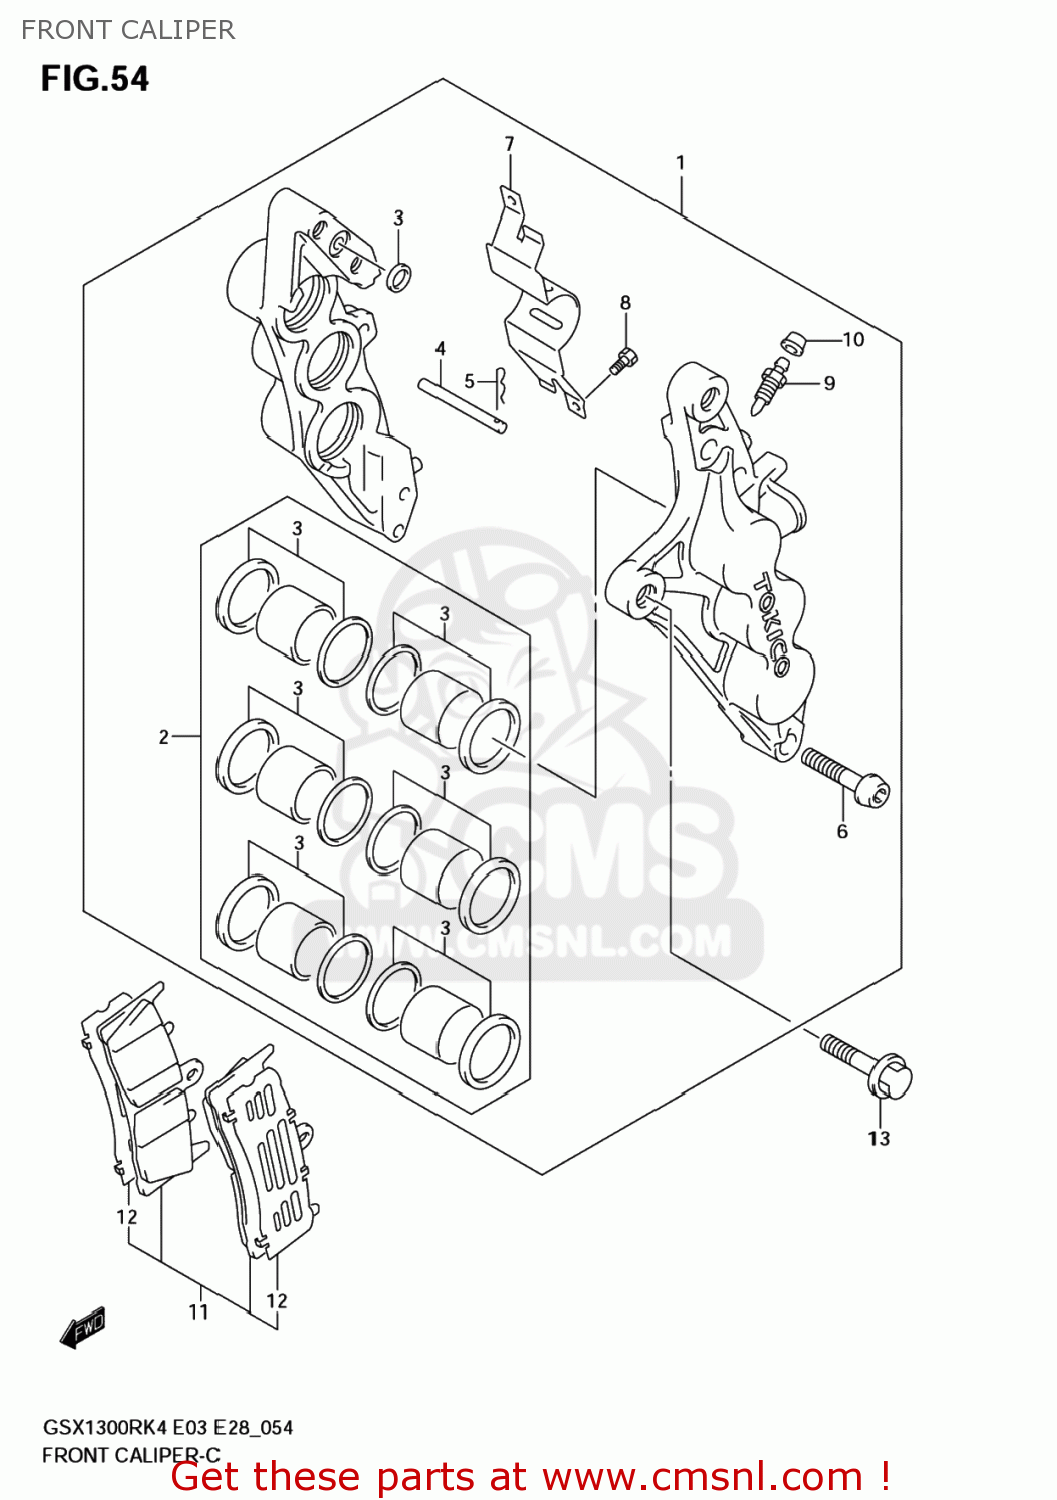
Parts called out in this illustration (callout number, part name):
1	CALIPER ASSY,FR,R(GOLD)
2	PISTON SET
3	SEAL SET,PISTON
4	PIN,PAD
5	CLIP,PAD PIN
6	BOLT
7	COVER,CALIPER
8	SCREW
9	BLEEDER
10	CAP,BLEEDER PLUG
11	PAD & SHIM SET (NAS)
12	SHIM,PAD
13	BOLT(10X30)
